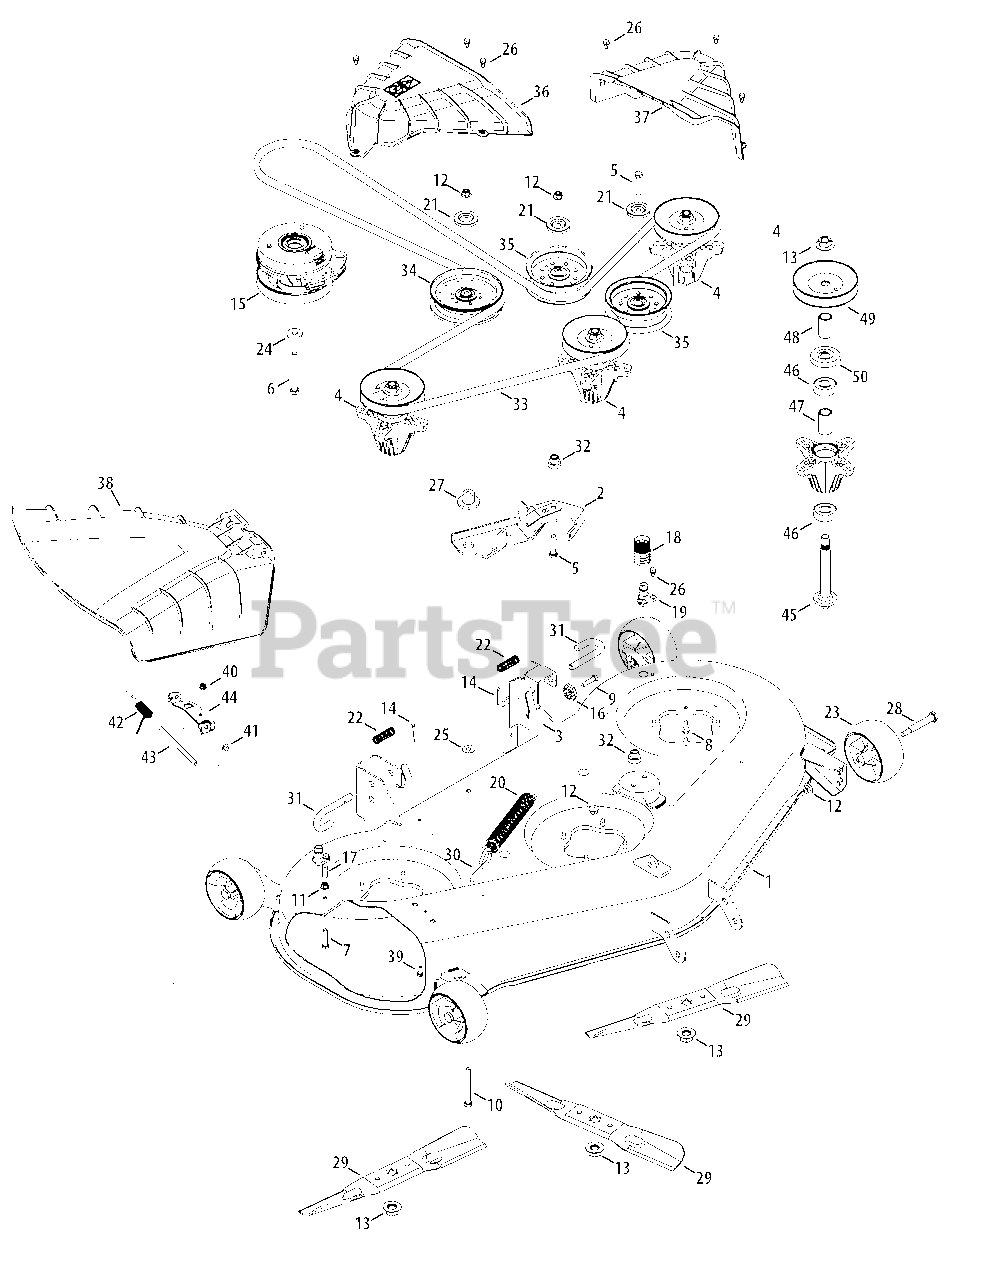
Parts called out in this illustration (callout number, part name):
1	50" Deck
2	Deck Idler Assembly
3	Deck Lift Bracket
4	Spindle Assembly
5	Hex Cap Screw, 3/8-16 x 1.75
6	Hex Cap Screw, 7/16-20 x 3.50
7	Hex Head Screw, 5/16-18 x 1.50
8	Hex Washer Screw, 5/16-18 x .750
9	Hex Flange Screw, 3/8-16
10	Hex Bolt 3/8-16 x 3.25"
11	Flange Lock Nut, 5/16-18
12	Flange Lock Nut, 3/8-16
13	HEX NUT
14	Cotter Pin, 5/32 x 1.25
15	Clutch, Electric PTO
16	Deck Adjustment Gear
17	Vinyl Cap, .29 x 1.00
18	Water Nozzle Adapter
19	Deck Wash Nozzle
20	Extension Spring, 1.25 OD x 1.751
21	Pulley Cap
22	Compression Spring, .66 x 1.9
23	Deck Ball Wheel, 5.0
24	Flat Washer, .450 x 1.25 x .164
25	Flat Washer, .385 x 1.0 x .030
26	Shoulder Screw, 1/4-20 x 0.50
27	Shoulder Spacer
28	Shoulder Screw, .5 x 2.5 x 3/8-16
29	Blade, Cut, 17.27" 2-In-1
29	Cub Cadet 50" HI LIFT BLADE SET
29	Genuine Factory Parts 50" BLADE SET
29	50" 6 PT STAR LOW LIFT/SAND BLADE
29	Cub Cadet 50" LOWLIFT BLADE SET
29	Genuine Factory Parts 50" LOWLIFT BLADE SET
29	50" 6 PT STAR XTREME MULCH BLADE
29	Cub Cadet 50" XTREME BLADE SET
29	Genuine Factory Parts 50" XTREME MULCH BLADE SET
30	Deck Spring Rod
31	Deck Hanger Rod
32	Shoulder Spacer
33	V-Belt
34	Idler Pulley, 5.00 Dia.
35	Pulley, Idler, 4.50" Dia.
36	Belt Cover, RH
37	Belt Cover, LH
38	Chute Deflector Assembly
39	SCREW 1/4-20 x .620 GR5
40	Nut, Flange Lock, 1/4-20, Nylon
41	PUSH CAP
42	Spring, Torsion, .440 ID x 1.75
43	Hinge Pin
45	Spindle Shaft, 6.11 Long
46	Ball Bearing
47	Spacer, .792 x 1.060 x 1.860
48	Spacer, .792 x 1.060 x 1.782
49	Deck Pulley
50	Bearing Shield
